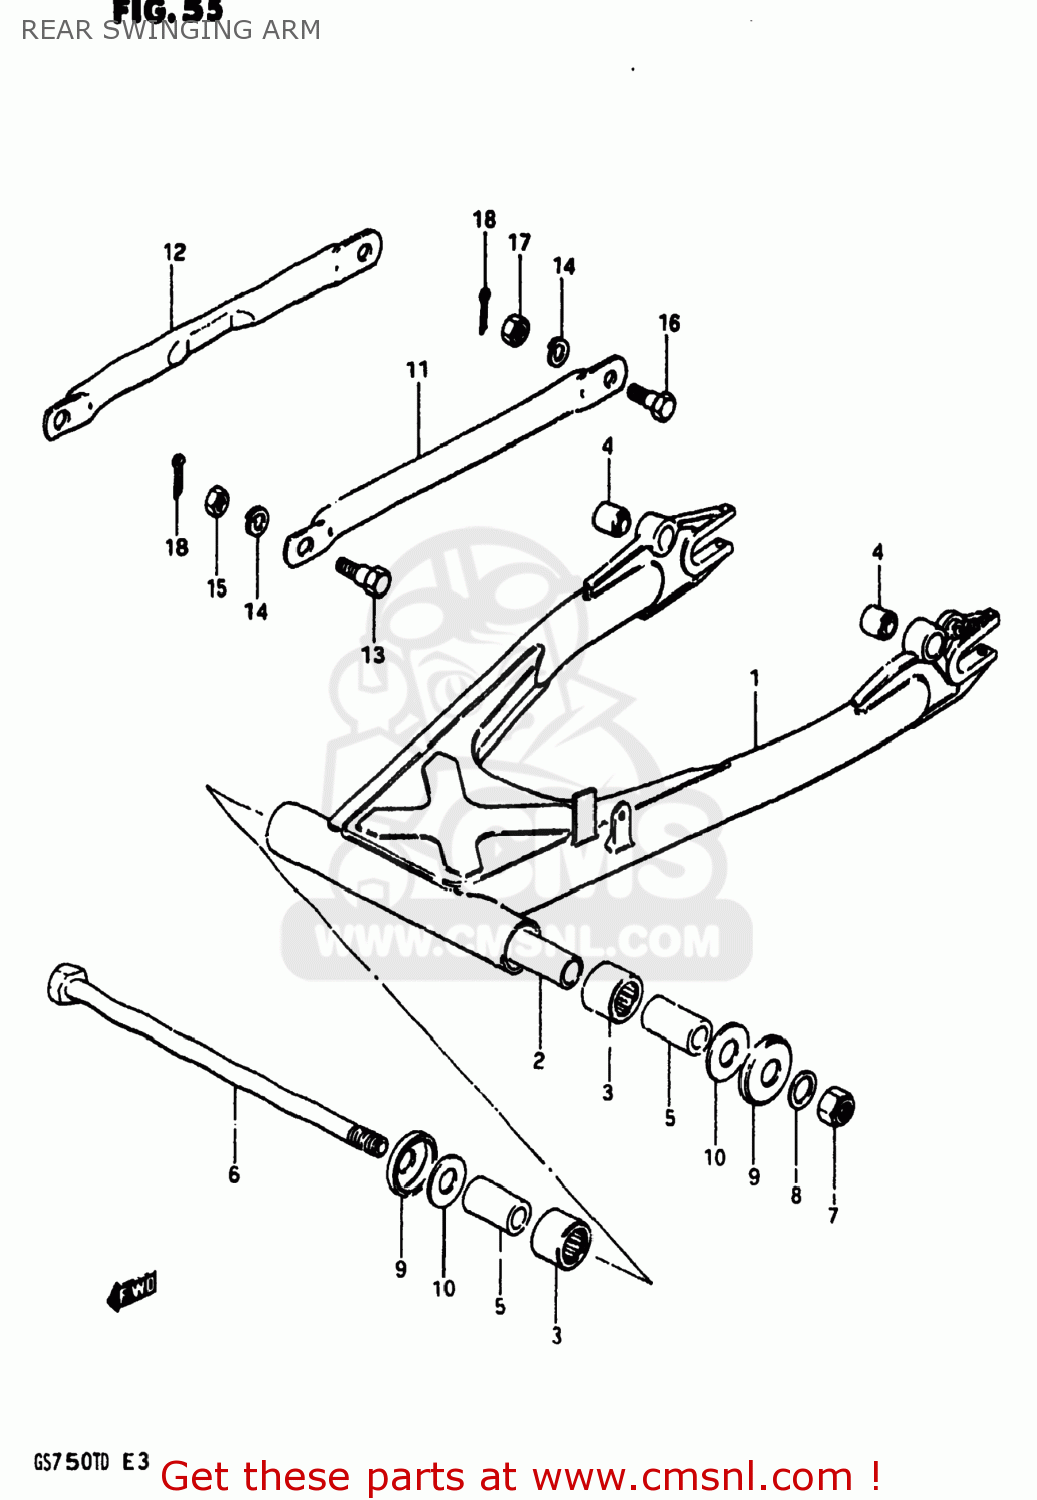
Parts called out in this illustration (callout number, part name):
1	SWING ARM ASSEMBLY,REAR
2	SPACER,RR SWGARM PIVOT CTR
3	BEARING(22X29X30)
4	BUSH
5	SPACER,RR SWGARM PIVOT
6	SHAFT,REAR SWING ARM
7	NUT 14MM
8	WASHER
9	CVR,RR SWGARM DUST SEAL(OD:40)
10	WASHER(14.2X34X1)
11	TORQUE LINK,REAR
12	LINK,REAR TORQUE
13	BOLT(10X24.5)
14	LOCK WASHER
15	NUT
16	BOLT(10X31)
17	NUT
18	PIN 20X20
